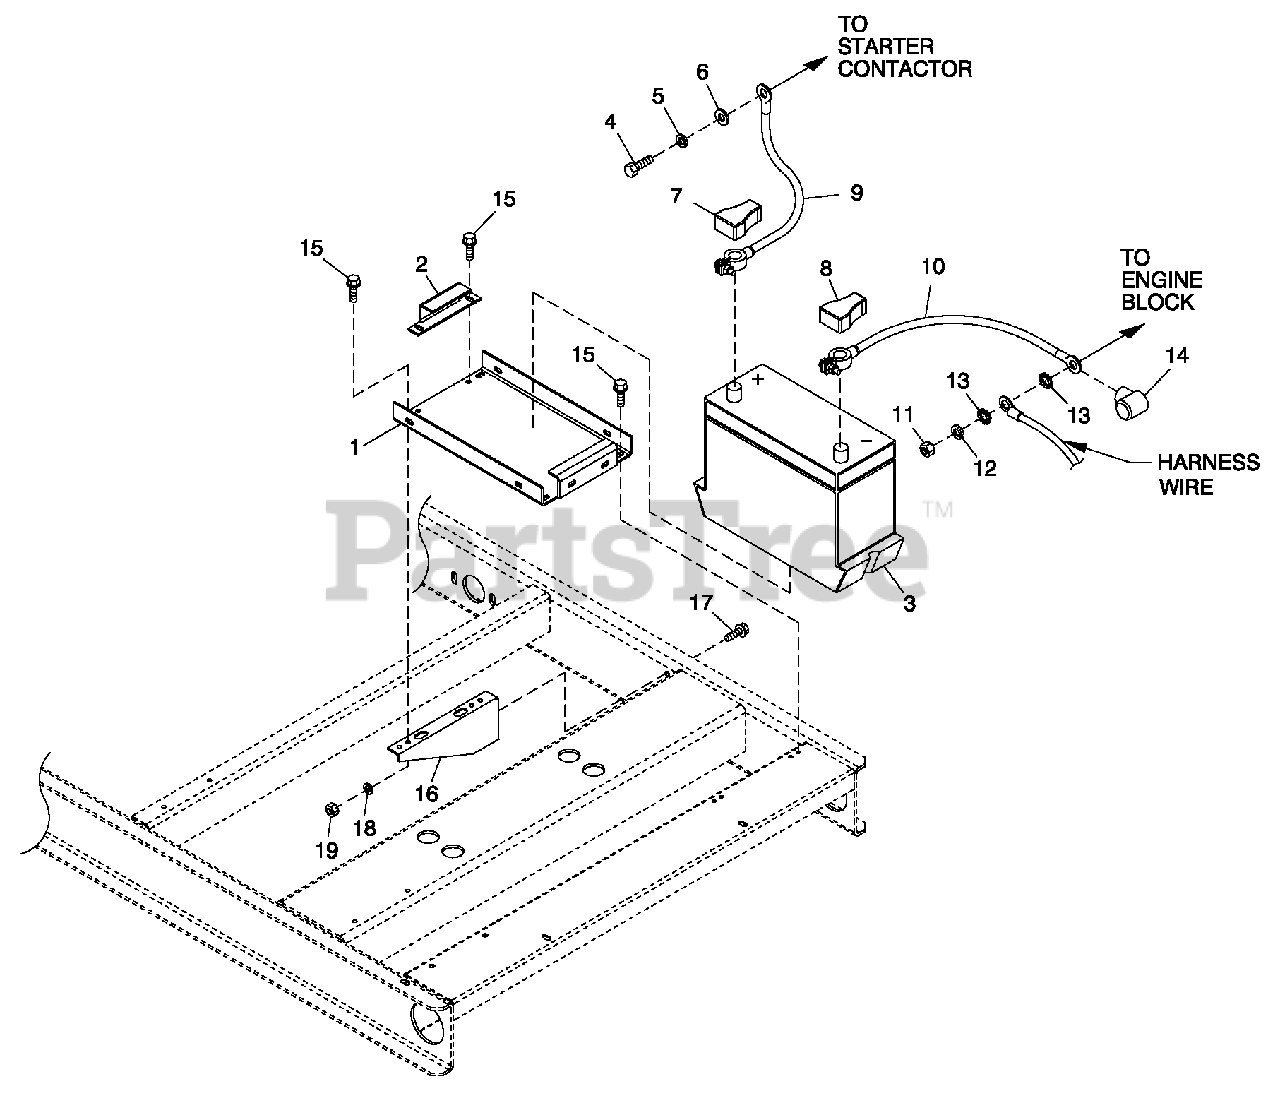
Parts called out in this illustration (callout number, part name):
1	TRAY BATTERY
2	STRAP BATTERY RETAINMENT
3	BATTERY 12VDC 24F 525 CCA
4	SCREW HHC 3/8-16 X 1 G8
5	WASHER LOCK 3/8
6	WASHER FLAT 3/8-M10 ZINC
7	BATTERY POST COVER RED +
8	BATTERY POST COVER BLACK -
9	CABLE BATTERY RED #1 X 35.00
10	CABLE BATTERY BLACK #1 X 40.00
11	NUT HEX M 8-1.25 G8 YEL CHR
12	WASHER LOCK M8-5/16
13	WASHER SHAKEPROOF EXT 5/16 STL
14	BOOT CONTACTOR CABLES
15	SCREW THF M6-1 X 16 N WA Z/JS
16	SUPPORT BATTERY TRAY
17	SCREW HHC M6-1.0 X 20 G8.8
18	WASHER LOCK M6-1/4
19	NUT HEX M6 X 1.0 G8 YEL CHR
